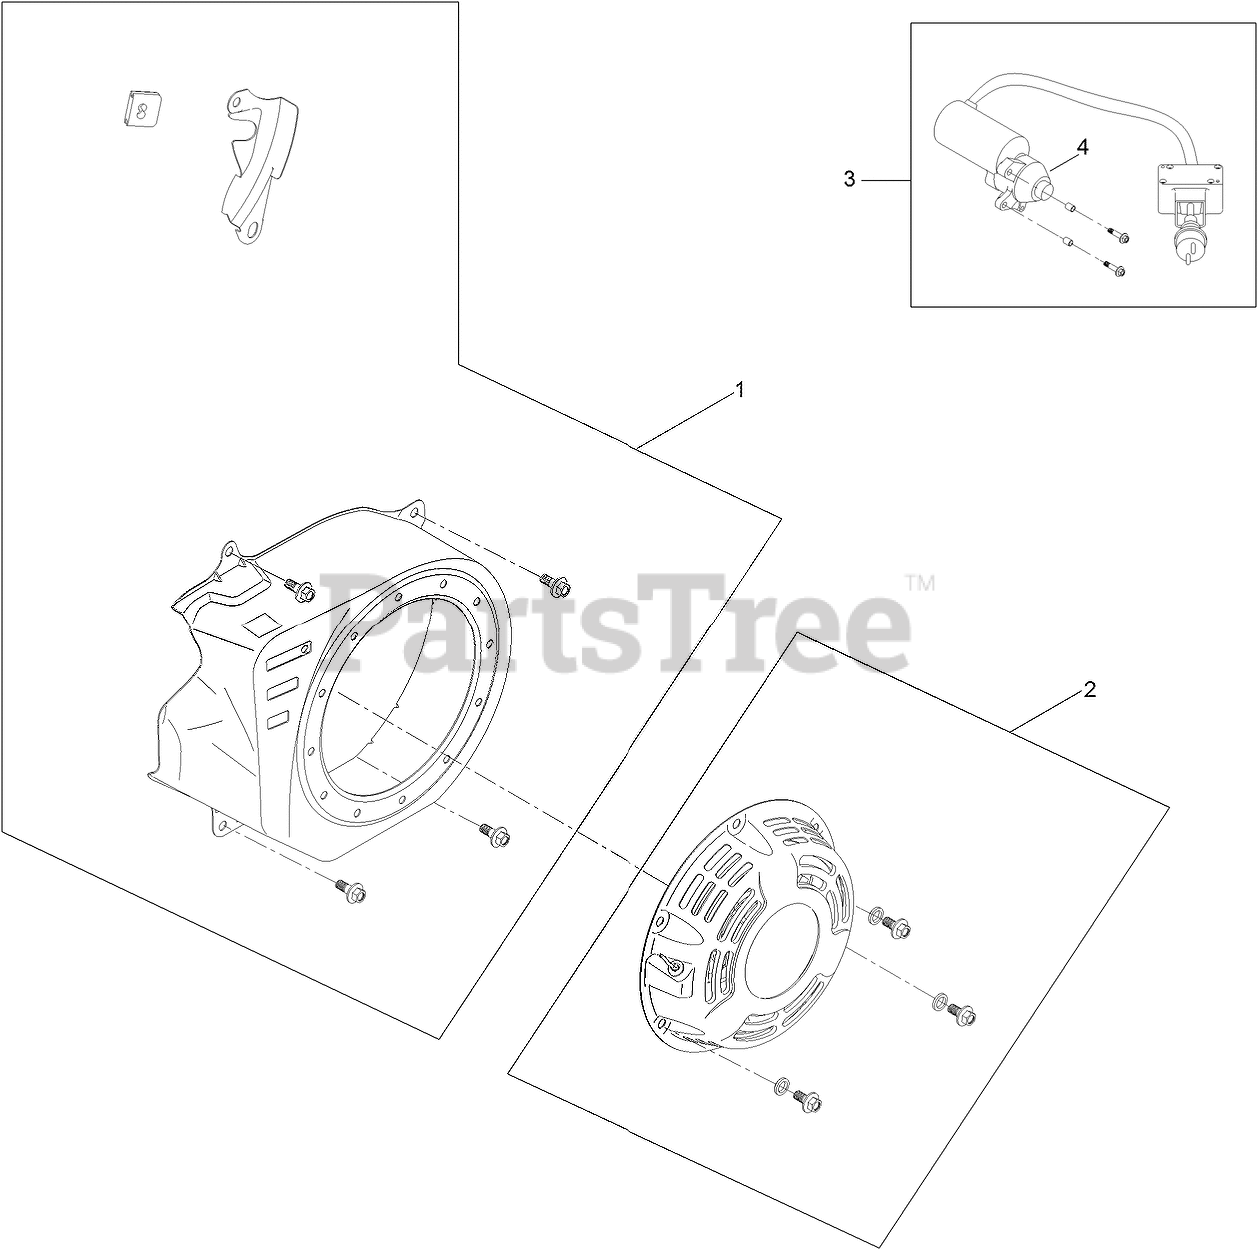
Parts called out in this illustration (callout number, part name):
1	BLOWER SHROUD KIT
2	RECOIL KIT
3	ELECTRIC STARTER KIT
4	PINION KIT
